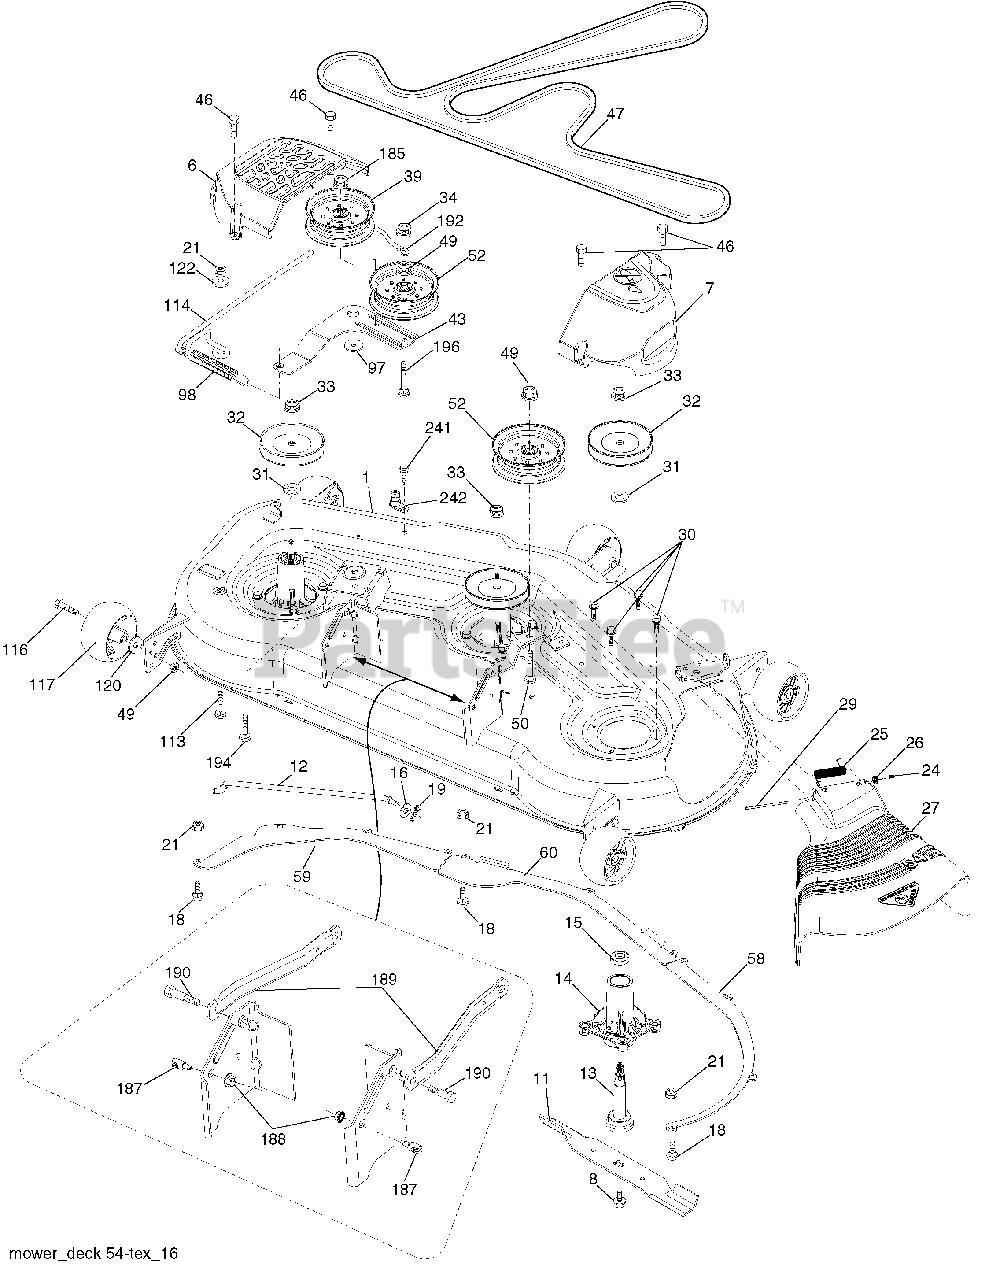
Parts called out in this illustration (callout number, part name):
1	Deck, Complete, 54"
1	Deck, Shell Only, 54"
6	Cover Mandrel LH
7	Cover Mandrel RH
8	Bolt 7/16 Asm. Blade
11	Blade Bagging
11	Blade Mulching
12	Rod Anti Sway
13	Shaft Asm. w/Lower Bearing
14	Housing, Mandrel
15	Bearing, Ball, Mandrel
16	Washer 3/8
18	Bolt Carriage 5/16-18 x 5/8
19	Pin Cotter 5/16 Bowtie
21	Nut, Crownlock 5/16-18 unc
24	Cap Sleeve
25	Spring, Torsion
26	Nut, Push
27	Deflector Shield
29	Rod, Hinge
30	Screw, Thdroll Washer Head
31	Washer, Spacer Mower Vented
32	Pulley, Mandrel
33	Nut, Flg. Top Lock
34	Nut Crownlock 3/8-16 unc
39	Pulley, Idler, Stationary LH
43	Arm, Idler
46	Screw, Thdroll. 1/4-20 x 5/8
47	Belt Deck Drive
49	Nut, Lock Flg. 3/8-16 unc
50	Bolt Rdhd Sqnk 3/8-16 unc x 2
52	Pulley Idler
58	Baffle Right
59	Baffle Left
60	Baffle Center
97	Washer Hardened
98	Spring Drive
113	Bolt Rdhd Sqnk 5/16-18 x 3/4
114	Rod Tension Relief
116	Bolt, Shoulder
117	Gauge Wheel
120	Washer 13/32 x 1-1/4 x 12 Ga.
122	Bushing Tension Relief
185	Nut Lock Flange 7/16-14 Gr. 5
187	Stud Fastener w/"D" Anti-Rotation
188	Nut Lock Hex Flange
189	Arm Susp. Mower Rear
190	Bolt Shoulder
192	Keeper Belt Idler
194	Bolt Carr Sqnk 7/16-24 x 2
196	Bolt Rdhd 3/8-16 x 2-1/2 Gr. 5
241	Screw
242	Washout Port
242	Coupling, Quick Connect
